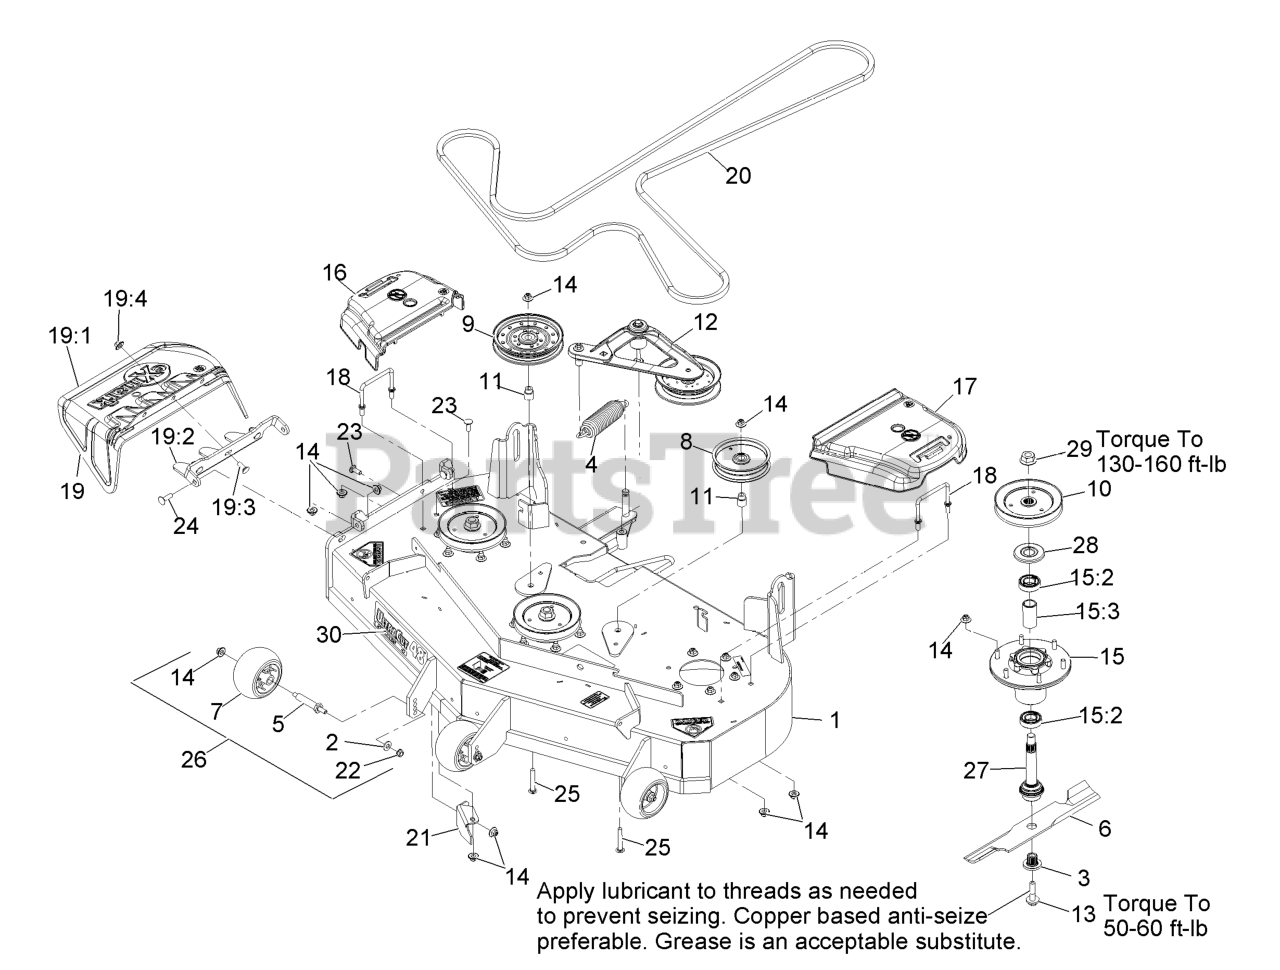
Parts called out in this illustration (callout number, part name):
2	WASHER-BELLEVILLE
3	BUSHING,SPLINED
7	ROLLER-SCALP, ANTI
8	PULLEY-IDLER
10	SHEAVE,BLADE DRIVE 5.90
11	BUSHING-IDLER
12	DECK IDLER ASM
13	SCREW,SEMS 1/2-20 X 2.19
14	Nut-Nyloc 3/8-16 Flg
15	ASM-CUTTER HSG WITH BEARINGS
15:2	BEARING-BALL
15:3	SPACER-BEARING
16	COVER-BELT, RH
17	COVER-BELT, LH
18	WIREFORM-COVER
19	ASM,DISCHARGE CHUTE
19:1	CHUTE,DISCHARGE
19:2	BRACKET,DISCHARGE CHUTE
19:3	SCREW-CARR
19:4	Nut-Nyloc 3/8-16 Flg
21	BAFFLE,DISCHARGE
22	NUT-HHF, WHIZ
23	SCREW-CARR
24	Bolt-Carriage 3/8-16 X 1 1/4
25	SCREW-CARR
27	ASM-SPINDLE AND SEAL
28	GUARD,BEARING TOP .989
29	NUT-FLANGE
30	DECAL,ULTRACUT 48 SERIES
